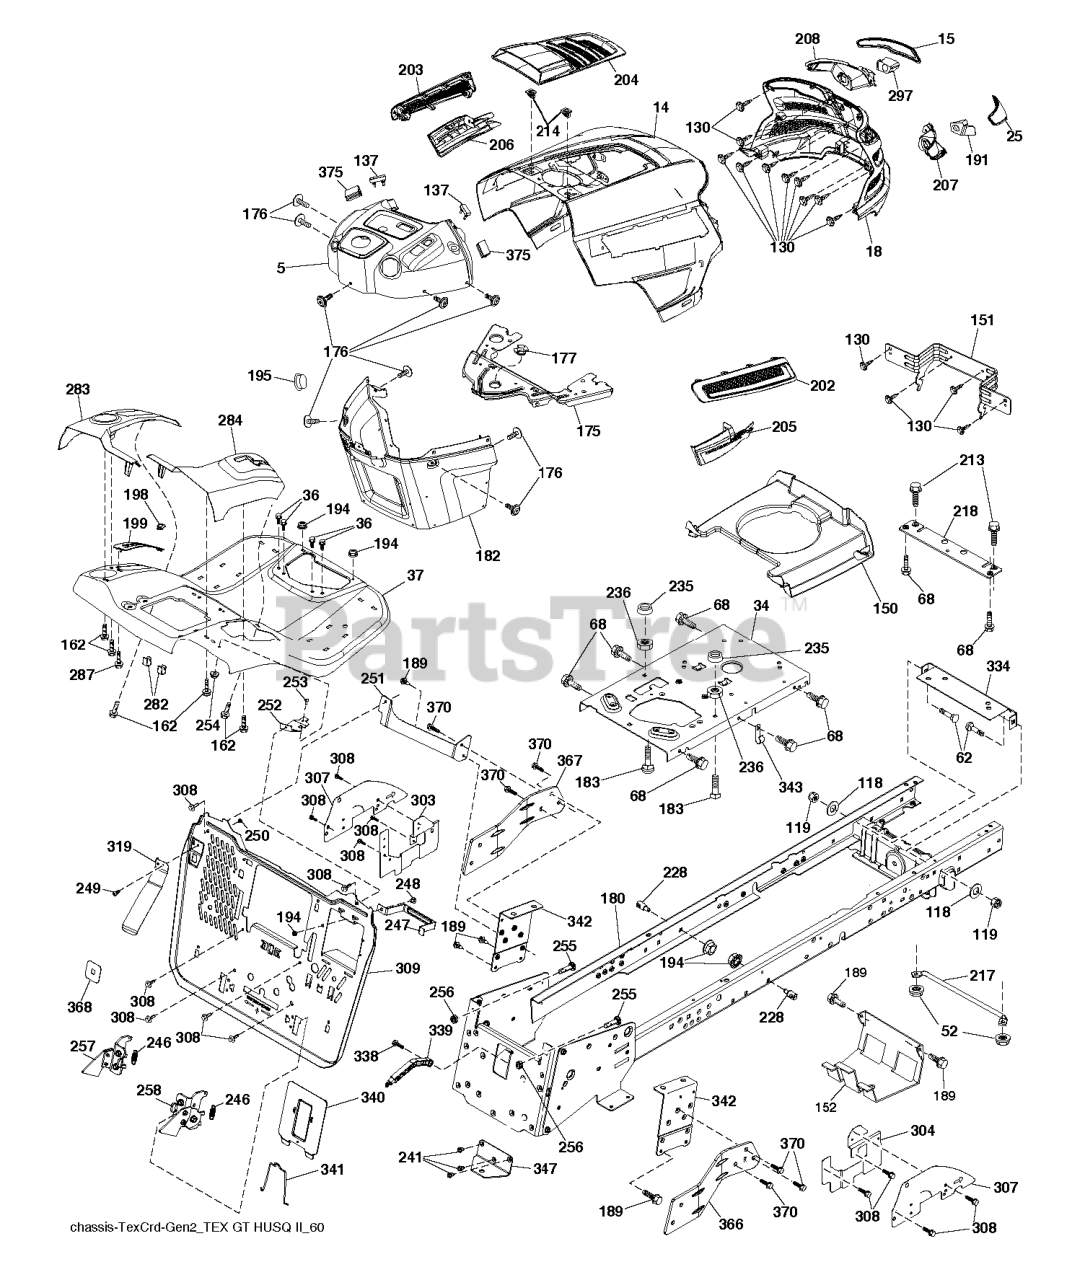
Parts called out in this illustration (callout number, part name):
5	DASH.GT.HUSQTX.SMM.RS.CH.498
14	HOOD.ASM.HUSQVARNA.GT.TEX.ORAN
15	LENS.HEADLIGHT.LH.GTII.2011
18	GRILLE.SUBSTRATE.2011.
25	LENS.HEADLIGHT.RH.GTII.2011
34	PLATE.ENGINE.10GA.CRD.GENII
36	SCREW 5/16"
37	FENDER.TEX.SRD.CRD.FRN.GUARDS
52	LOCKNUT
62	BOLT D
68	SCR 5/16-18 X 1/2 SELFTAP ZN
118	WASHER
130	SCREW.#10 X 0.750.BOS
137	BUMPER DASH
150	AIR.DUCT.GTV.BLACK
151	BRACKET.PIVOT.HOOD.GT.HUSQ.II
152	SHIELD.BROWNING.W/TEX
162	SCREW.HI-LO.CONSOLE
175	PLATE.PNT.CROSSMEMBER.HUSQ/PRE
176	SCREW.#10-24X5/8.RN.QU
177	BUSHING STEERING
180	WELDMENT.CHASSIS.TEX.CRD.GEN.2
182	DASH LOWER.HUSQ.PRED NO CRUISE
183	BOLT.5/16-18X1-1/4 FULL THD
189	SCREW
191	INSERT.REFLECTIVE.RH.HUSQ.GTII
194	NUT LOCK HEX FLANGE 5/16-18
195	PLUG.HOLE.DASH.LOWER.12V.BLK
198	INDICATOR.DECK.LIFT.RED
199	PLATE DECK LIFT
202	VENT.SIDE.RH.GT.HUSQ.II.
203	VENT.SIDE.LH.GT.HUSQ.II.498
204	VENT.TOP.ASM.HUSQ.GT2
205	SIDE.TRIM.RH.GT.HUSQ.II
206	SIDE.TRIM.LH.GT.HUSQ.II.GRAY
207	BEZEL LIGHT.RH.GT.II.MYLAR
208	BEZEL LIGHT.LH.GT.II.MYLAR
213	BOLT
214	CLIP.RETAINER.TINNER.
217	ROD.PIVOT.HOOD
218	X-PIECE.HOOD.STOP.NON/
228	STUD.FASTNER.W/ANTI-ROTATE
235	SPACER FENDER
236	NUT.CENTERLOCK.5/16-
241	SCREW 5/16-18X1
246	SPRING.LTCH.BGR.GEN2.5.CRD.TEX
247	STRAP.BATTERY.TCRD.GEN2.5X431
248	BOLT.CARR.5/16-18X1/2
249	SCREW.BUTTONHD.10-24X1/2.(2 2)
250	NUT 10-24 NYLOC
251	BRACKET.PNT.LH.SUPP.BKPLT.EDIP
252	BRACKET.PNT.RH.SUPP.BKPLT.EDIP
253	1/4-20X3/4 CARR BLT
254	NUT T
255	BOLT CROSS DRILLED CUP HEAD SQ
256	NUT.HEX.3/8-16
257	LATCH.ASM.BGR.LH.GEN2.5.STMPD
258	LATCH.ASM.BGR.RH.GEN2.5.STMPD
282	CLIP.RETAINER.CONSOLE.LT.HUSQ
283	CONSOLE.DECKLIFT.CRDII.498
284	CONSOLE.PEDAL.HYDRO
287	SCREW 1/4X20
297	INSERT.REFLECTIVE.LH.HUSQ.GTII
303	SHIELD.LWR.LH.LT.30DECK.CRDSRD
304	SHIELD ISO EURO RH LOWER CRD
307	SHIELD.UPPER.CRD.SRD.ISO
308	BOLT.5/16-18UNCX3/4 W/SEMS.BLK
309	BACKPLATE.TEXCRD2.5.BAGGER.479
319	LEVER.PRSNC.BGR.TEX.CRD.GEN2.1
334	BRACKET.ENGINE
338	BOLT BOLT SHOULDER
339	LEVER LEVER BAGGER
340	BATTERY.DOOR.TCRD.GEN2.5.MS479
341	LATCH.BATTERY.DOOR.TCRD
342	SUPPORT.PNT.FENDER.CRD.TEX
343	CLIP CLIP
347	HITCH HITCH TOW TEX CRD GEN 2
366	BRACKET.RH.FRONT.BAGGER.BLACK
367	BRACKET.LH.FRONT.BAGGER.BLACK
368	FULL.LEVER.BAGGER.TEX.CRD
370	SCREW 3/8-16X1
375	BUMPER CLIP-ON. DASH 1"
